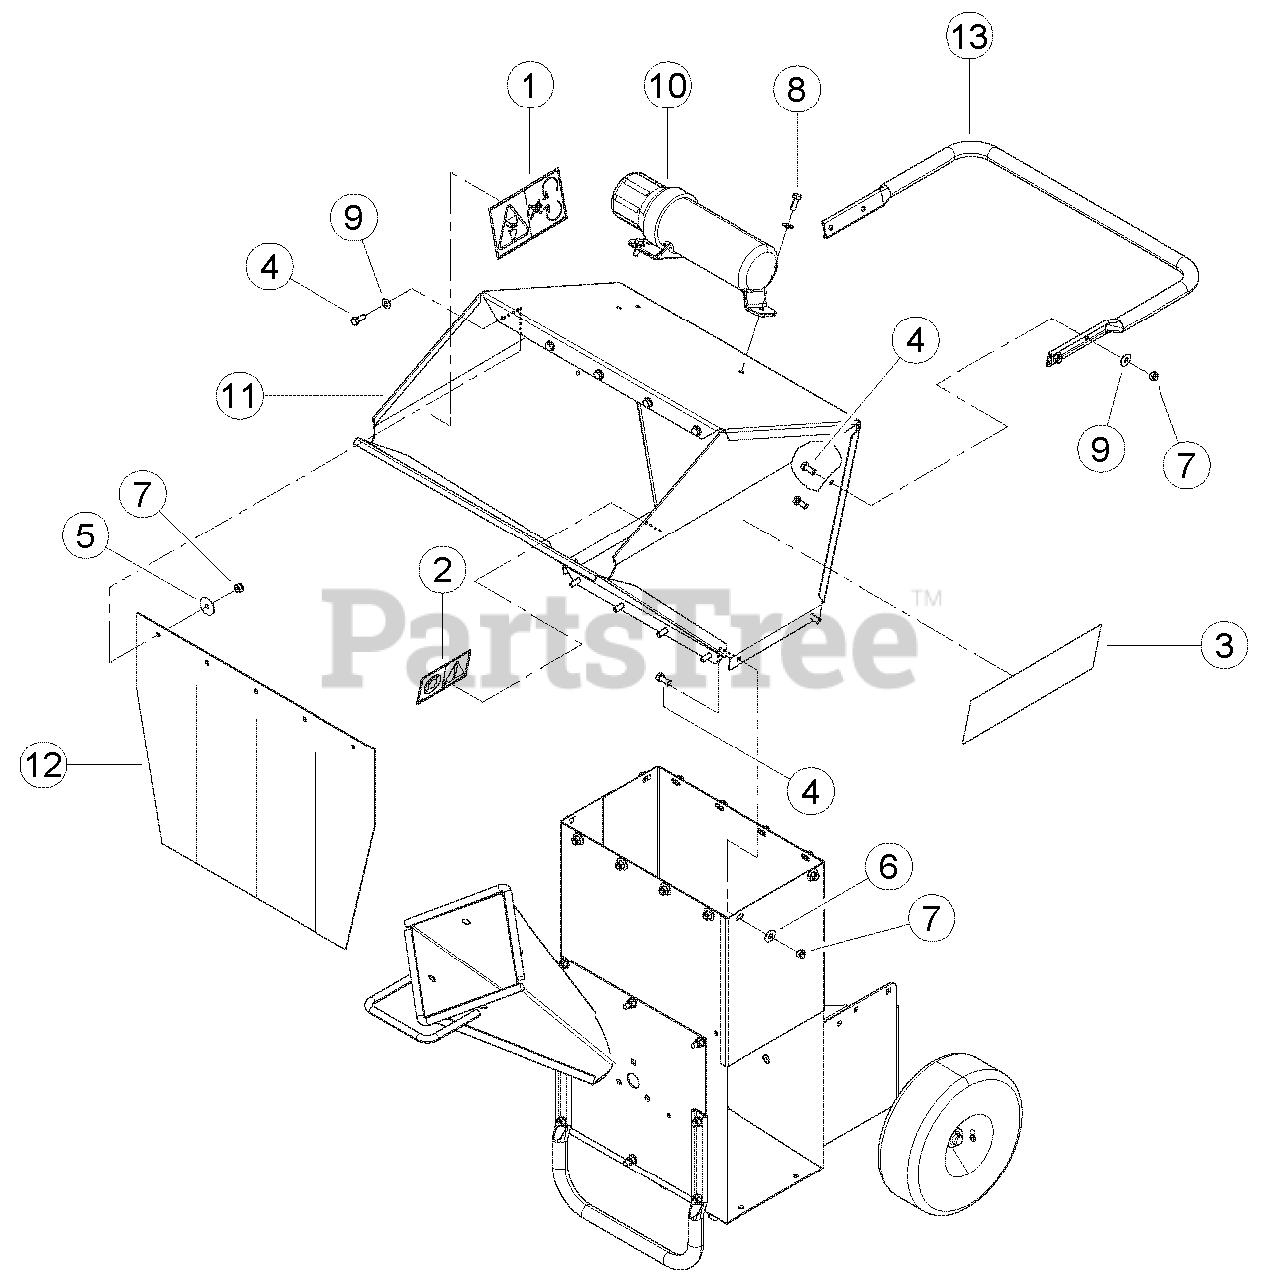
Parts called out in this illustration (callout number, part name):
1	DECAL, BLADE DANGER ISO
2	DECAL, SHREDDER SIZE ISO
3	DECAL, ECHO BEARCAT 12.00 X 4.00
4	BOLT, 5/16 X 3/4 HEX HD GR5 ZP
5	WASHER, 5/16 FENDER ZP
6	WASHER, 5/16 FLAT ZP
7	NUT, 5/16 NE NYLOCK ZP
8	BOLT, 5/16 X 7/8 HHCS GR5 NC ZP
9	WASHER, 5/16 SAE FLAT ZP
10	CONTAINER, MANUAL
11	WELDMENT, WIDE CE COMPLIANT HOPPER
11	WELDMENT, NARROW GB HOPPER (SC3206)
12	BELTING, CE COMPLIANT HOPPER
13	HANDLE, CE COMPLIANT HOPPER
